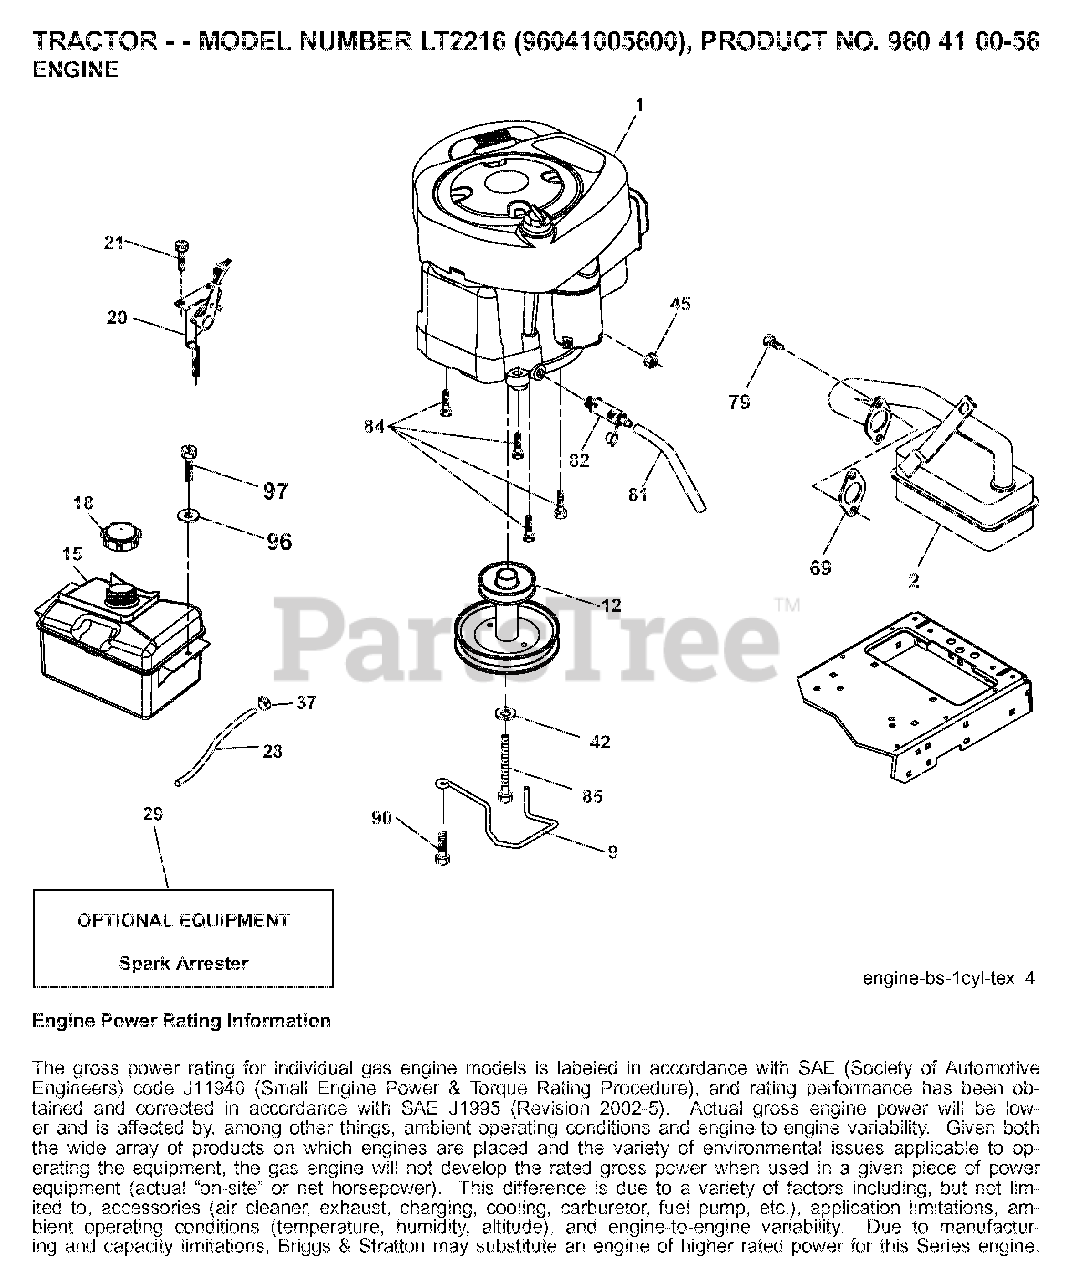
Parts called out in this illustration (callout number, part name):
9	KEEPER.BELT.ENGINE.3.25
12	PULLEY ENGINE
15	TANK FUEL FRT 1.5 GAL
18	FUEL CAP
20	CONTROL.TH/CK.C.
21	SCREW
28	LINE.FUEL.20
29	ARRESTER SPARK (OPTIONAL)
37	HOSE CLAMP
42	LOCKWASHER
45	NUT
69	REPL BY 532 27 22-93
79	SCREW.SOCKET HD.5/16-1
81	TUBE, DRAIN OIL ASM.
82	PLUG DRAIN OIL EASY
84	SCREW.3/8-16
85	BOLT HEX 7/16-20X4-1/4"
90	SCREW 3/8-16X1
97	SCREW HEXWSHR 1/4-20X3/4
